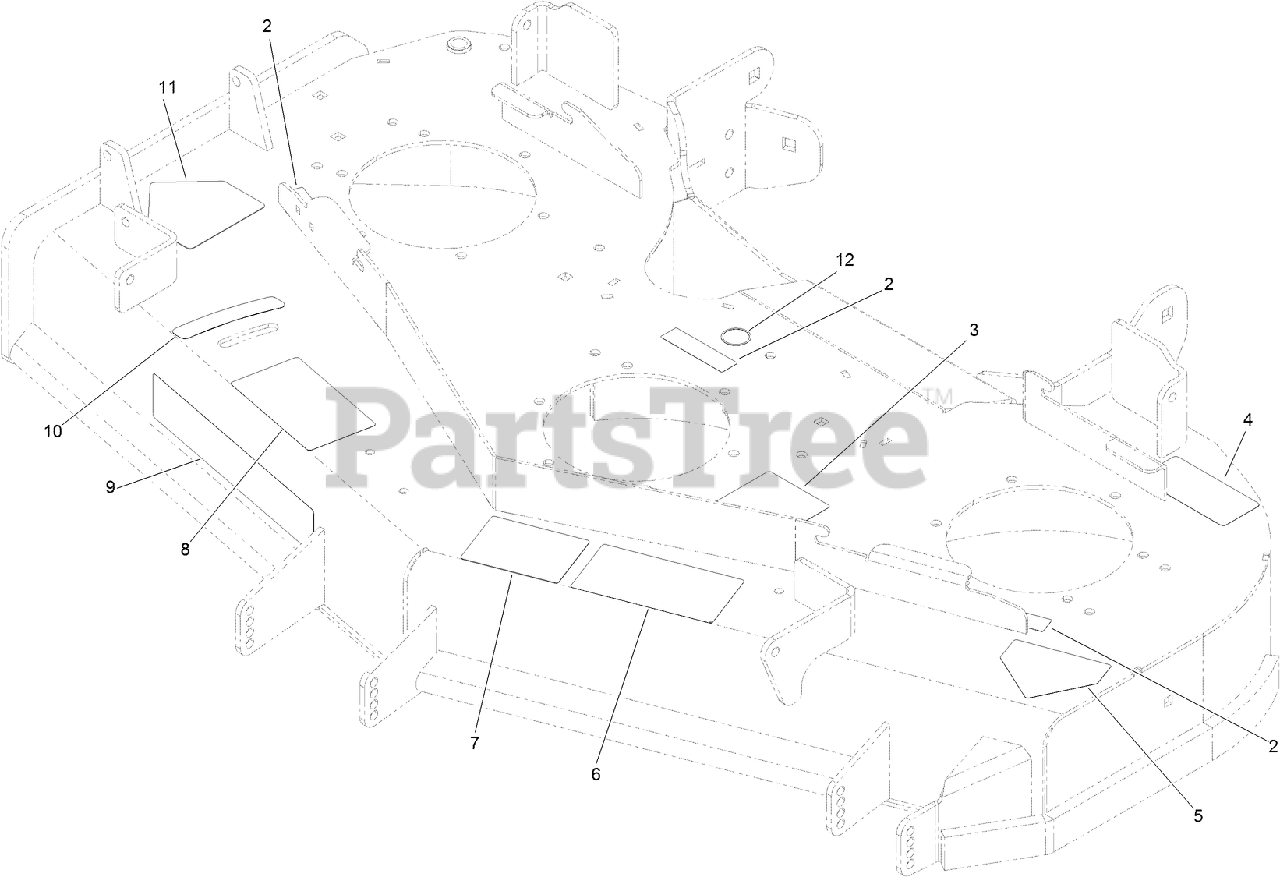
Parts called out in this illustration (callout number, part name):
2	DECAL-COVER, MISSING
3	DECAL-ROUTING, DECK BELT
4	DECAL-TORQUE
5	DECAL-DANGER
6	DECAL-DANGER, THROWN OBJECT
7	DECAL-SCALP, ANTI
8	DECAL-ADJUSTMENT, BAFFLE
10	DECAL-SETTING, BAFFLE
11	DECAL-DANGER
12	DECAL-GREASE
